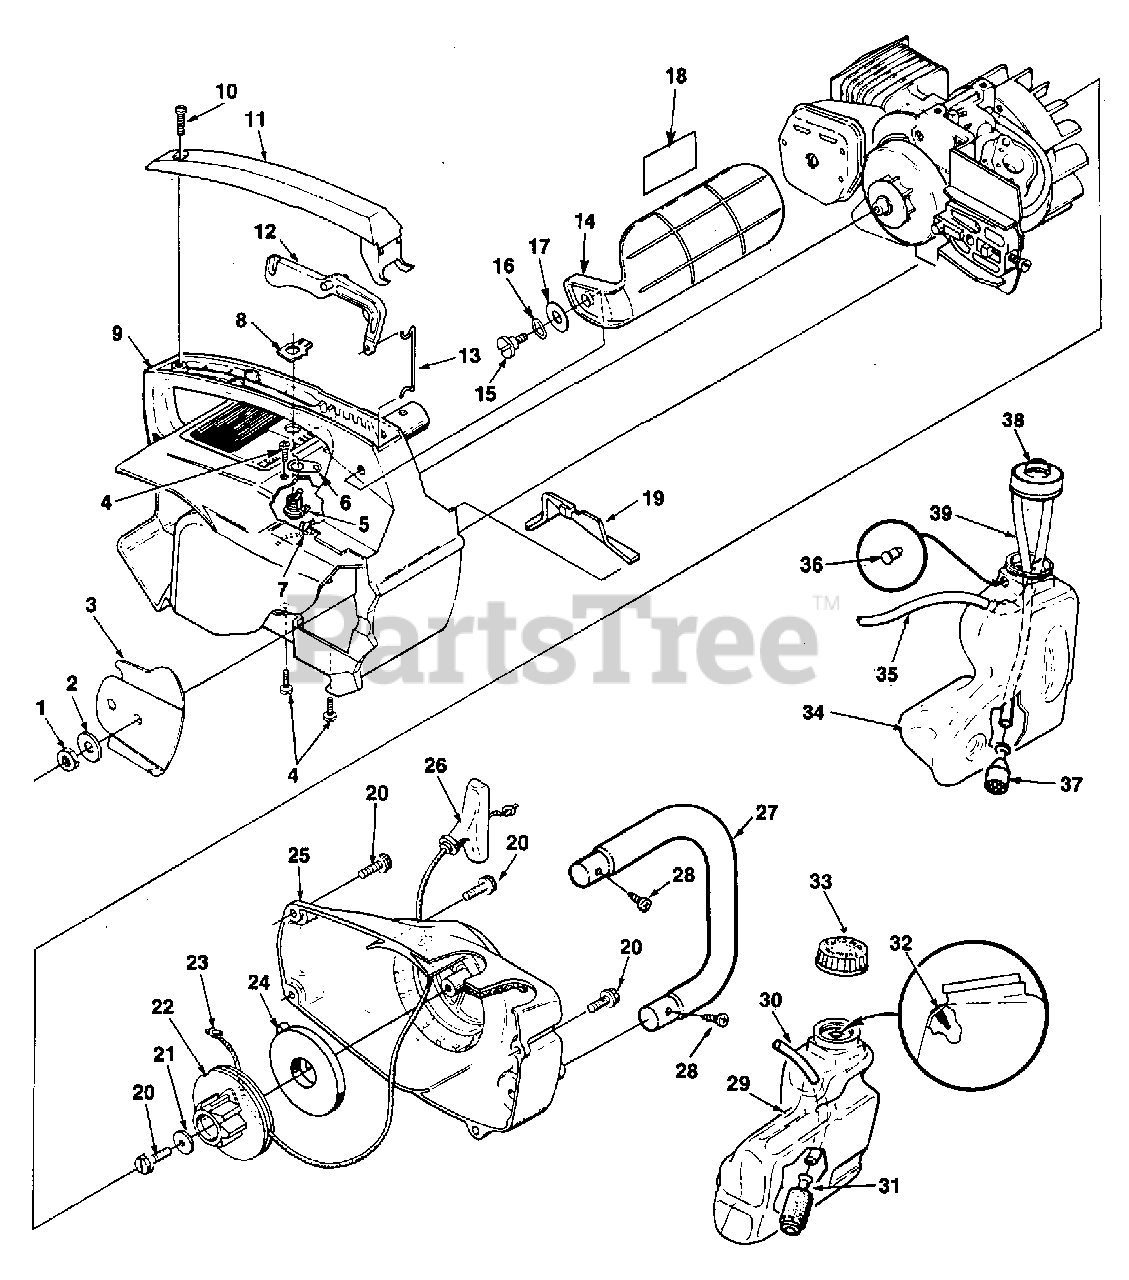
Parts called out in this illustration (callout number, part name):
1	NUT- Guide Bar
2	WASHER- Flat
3	PLATE- Guide Bar
4	SCREW- Pan hd. (10-24 x 3/4")
5	SWITCH- Toggle
6	STRAP- Ground
7	GROUND LEAD
8	PLATE-"On-Off"
9	HOUSING- Engine
10	SCREW- Pan hd. (#10 x 5/8")
11	COVER- Handle
12	TRIGGER
13	ROD- Throttle (UT-10705)
14	HAND GUARD
15	SCREW- Shoulder (#10 x .560)
16	WASHER- Curved spring
17	WASHER- Flat
18	DECAL- Handguard
19	COVER- Air filter
20	SCREW- Thd. form (10-14 x 3/4")
21	WASHER- Retaining
22	PULLEY- Starter
23	ROPE- Starter
24	SPRING- Rewind
25	HOUSING- Rewind Starter w/decals
26	GRIP- Starter
27	HANDLE BAR
28	SCREW- Pan hd. (10-16 x 3/4")
29	FUEL TANK
30	TUBING- Rubber (7")
31	FILTER- Fuel
32	VALVE- Duck bill
33	FUEL CAP
34	OIL TANK
35	TUBING- Rubber (10")
36	VALVE- Duck bill
37	OIL FILTER
38	OILER & CAP
39	TUBING- Rubber (7")
